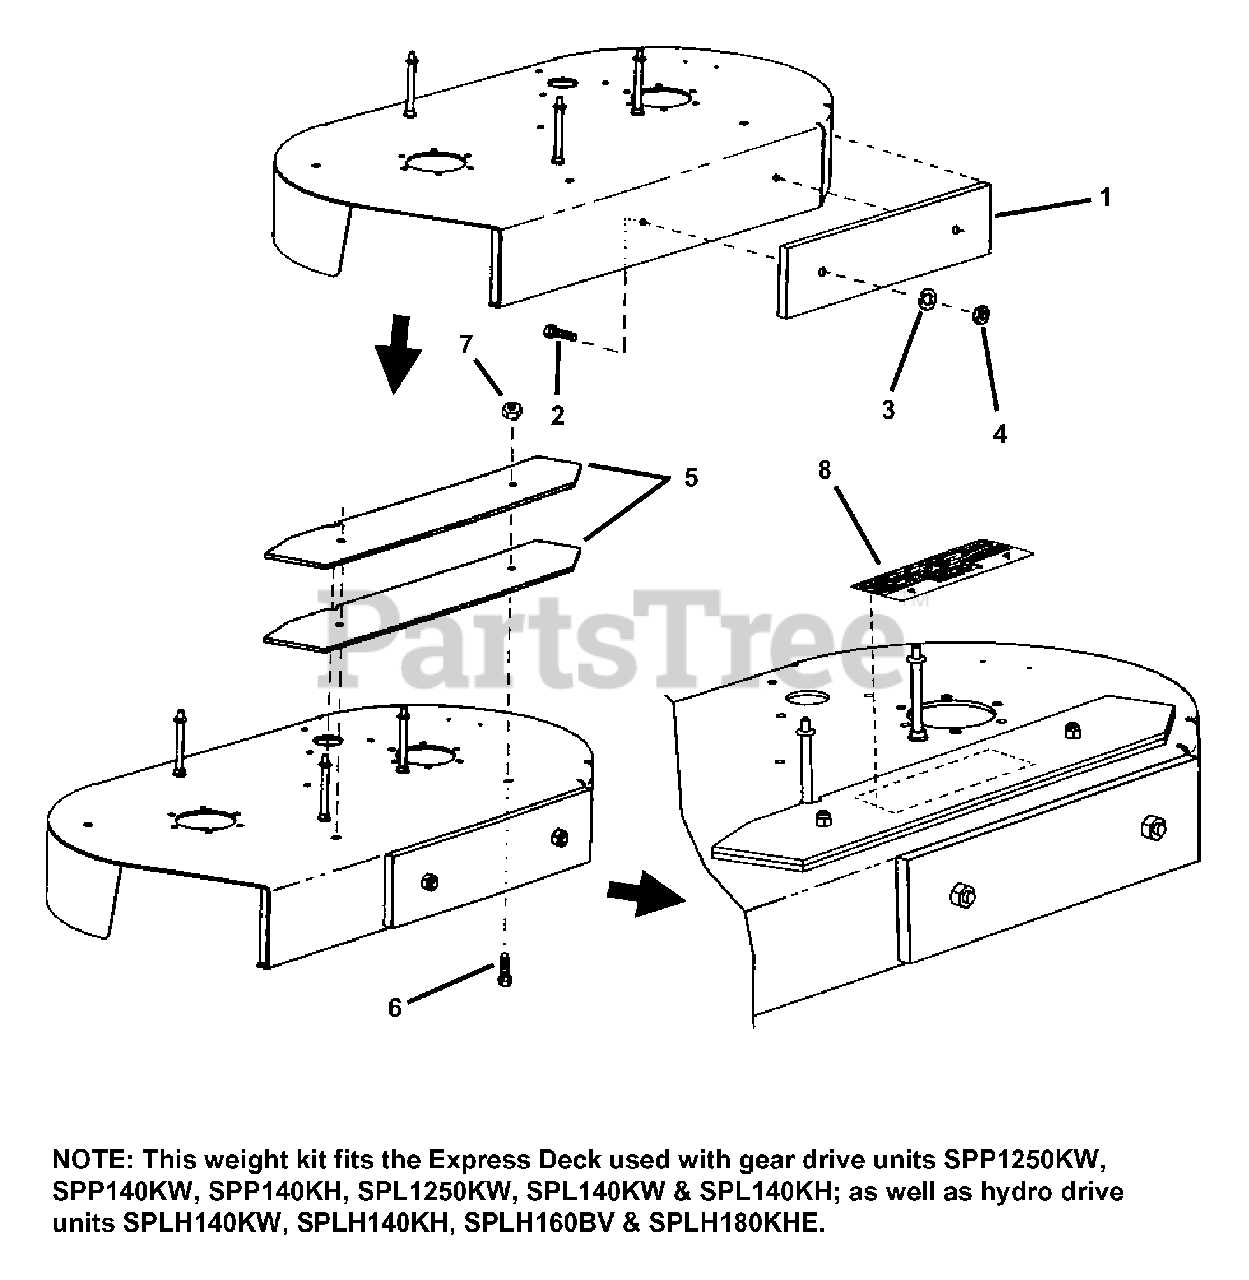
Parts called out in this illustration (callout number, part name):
1	WEIGHT, Front, PRO 36" Deck (painted)
2	SCREW, 1/2-13 x 1-1/2" Hex Head Cap
3	WASHER, 1/2" Split Lock
4	NUT, 1/2-13 Hex, Grade 5
5	WEIGHT, Top
6	BOLT, 3/8-16 x 1-1/4" Short Neck Carriage, Grade 5
7	NUT, 3/8-16 Hex Nyloc
8	DECAL, Caution Guard/Catcher
